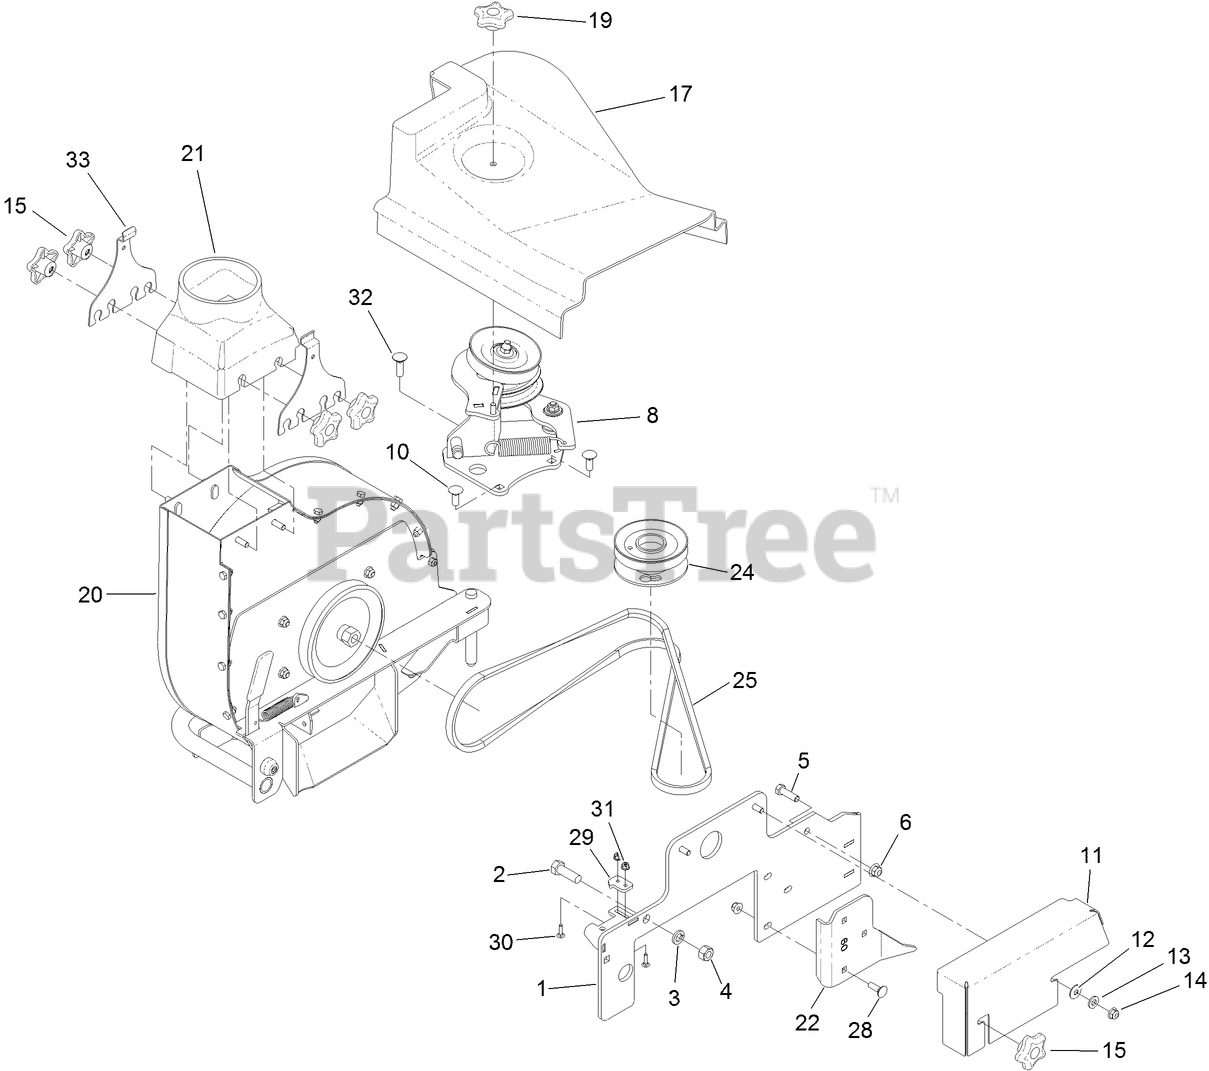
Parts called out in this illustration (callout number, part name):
1	MOUNT-DECK, BLOWER
2	SCREW-HH
3	WASHER-LOCK
4	NUT-HH
5	SCREW-HH
6	NUT-HF, NI
8	IDLER ASM
10	BOLT-CARR
11	GUARD-BELT, BLOWER
12	WASHER-BELLEVILLE
13	WASHER-RUBBER
14	NUT-HF, NI
15	KNOB-HANDLE
17	COVER-BELT
19	KNOB-HANDLE
20	BLOWER ASM
21	TRANSITION-BLOWER
24	PULLEY-BLOWER
25	BELT-V
28	BOLT-CARR
29	PLATE-LATCH
30	SCREW-CARR
31	NUT-HF
32	BOLT-CARR
33	CLAMP-HOSE
